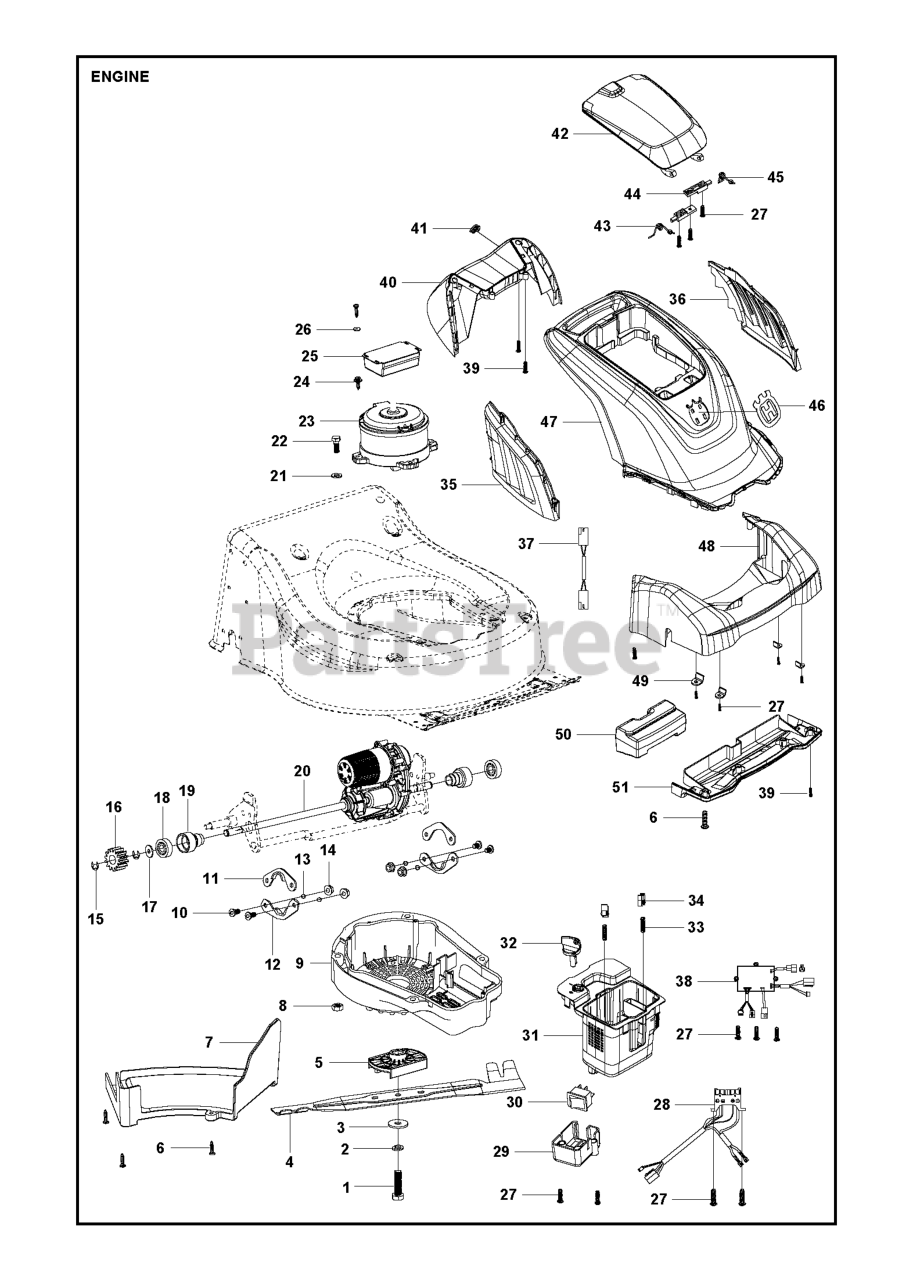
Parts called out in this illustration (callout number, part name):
2	SPRING WASHER
4	MOWER BLADE MULCH 40CM PRODUCT
5	BLADE SUPPORT
7	COVER LOW PROTECT # 2106100379
8	NUT LOCKING
10	SCREW M6*16 #26800204601
11	FIXING PLATE #26300314601
12	FIXING PLATE #26300124401
13	O-RING #25100175201
14	LOCK NUT M6,GB/T6187.1-2000 #2
15	WASHER Ï?9,GB896 #26800900201
16	GEAR #26900215601
17	WASHER Ï?12.8*Ï?20*0.8 #268007
19	BEARING HOUSING #26900211501
20	GEARBOX ASSY #23050206401
30	KEY SWITCH
31	BOX BATTERY BOX
34	CAP COMPRESSION SPRING CAP
35	COVER RIGHT AIR WINDOW PLATE
36	COVER LEFT AIR WINDOW PLATE
37	LINE CONNECTING # 27100124701
38	PRINTED CIRCUIT ASSY SEL-PROPE
40	COVER BACK COVER
42	COVER BATTERY LID
43	TORSION SPRING
44	HINGE BATTERY LID HINGE
45	TORSION SPRING LEFT
46	DECAL LOGO
47	COVER MOTOR COVER
48	COVER FRONT COVER
50	WEIGHT # 25100184101
51	COVER FRONT HANDLE (UNDER SIDE
